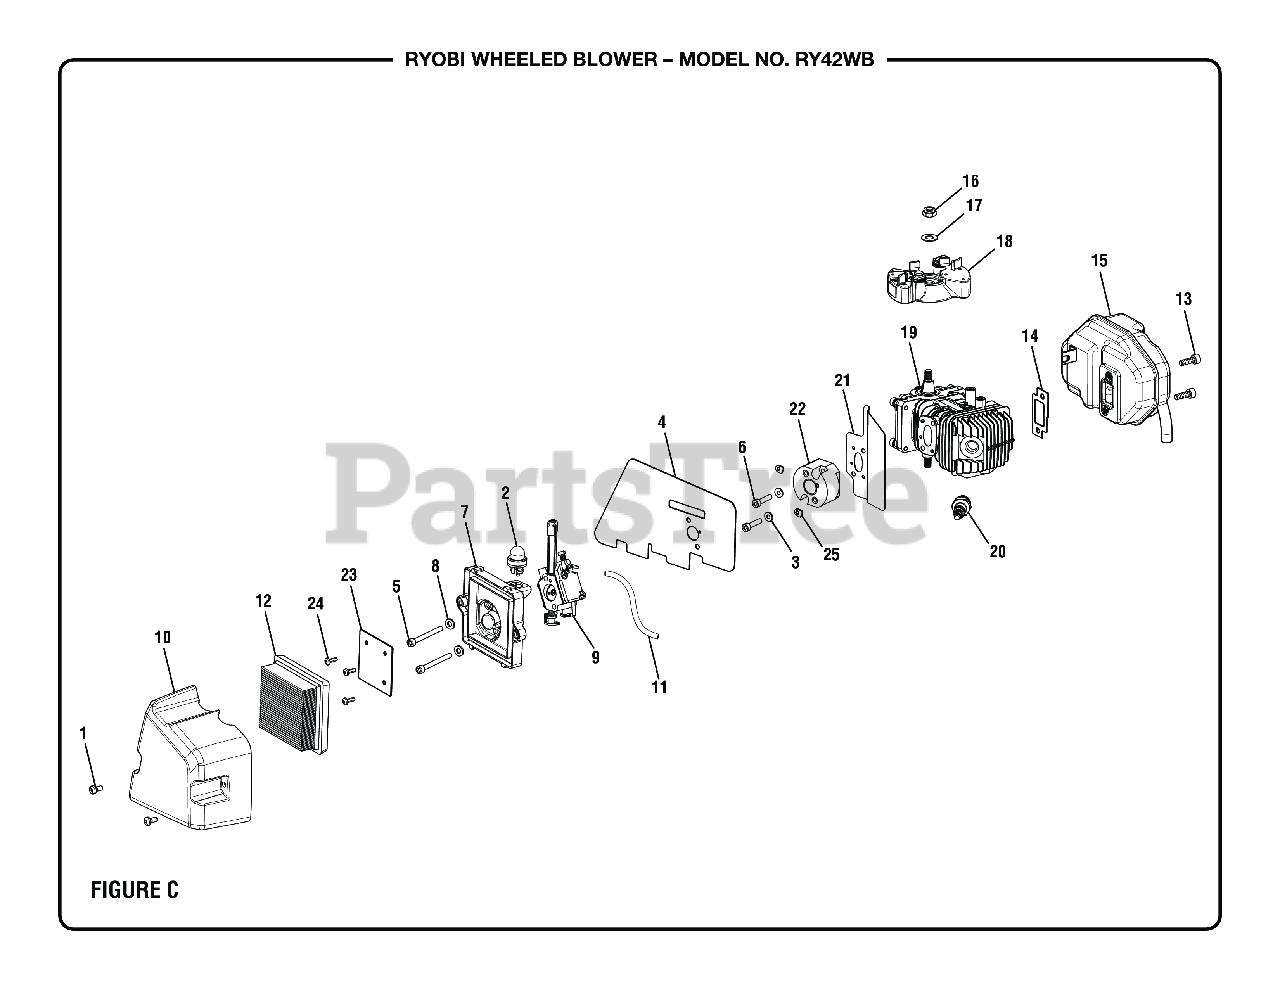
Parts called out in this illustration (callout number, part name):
1	Screw (M5, Special)
2	Primer Bulb Assembly
3	Spring Washer (M5)
5	Screw (M5 x 50 mm, Torx Slotted Recessed Pan Hd.)
6	Screw (M5 x 0.8 in.)
7	Air Box Base
8	Washer (ID5.8 x OD11.5 x 1.7t)
9	Carburetor
10	Air Box Cover
11	Fuel Line
12	Air Filter
13	Screw (1/4-20 x 5/8 in.)
15	Exhaust Assembly
16	Lock Nut (M8)
17	Washer (ID9 x OD17.7 x 1.1t)
18	Flywheel Assembly
19	Short Block Assembly
20	SPARK PLUG (CHAMPION RCJ4)
24	Screw (M4 x 12 mm, Slotted Recessed Pan Hd.)
25	Washer (Heat Dam)
